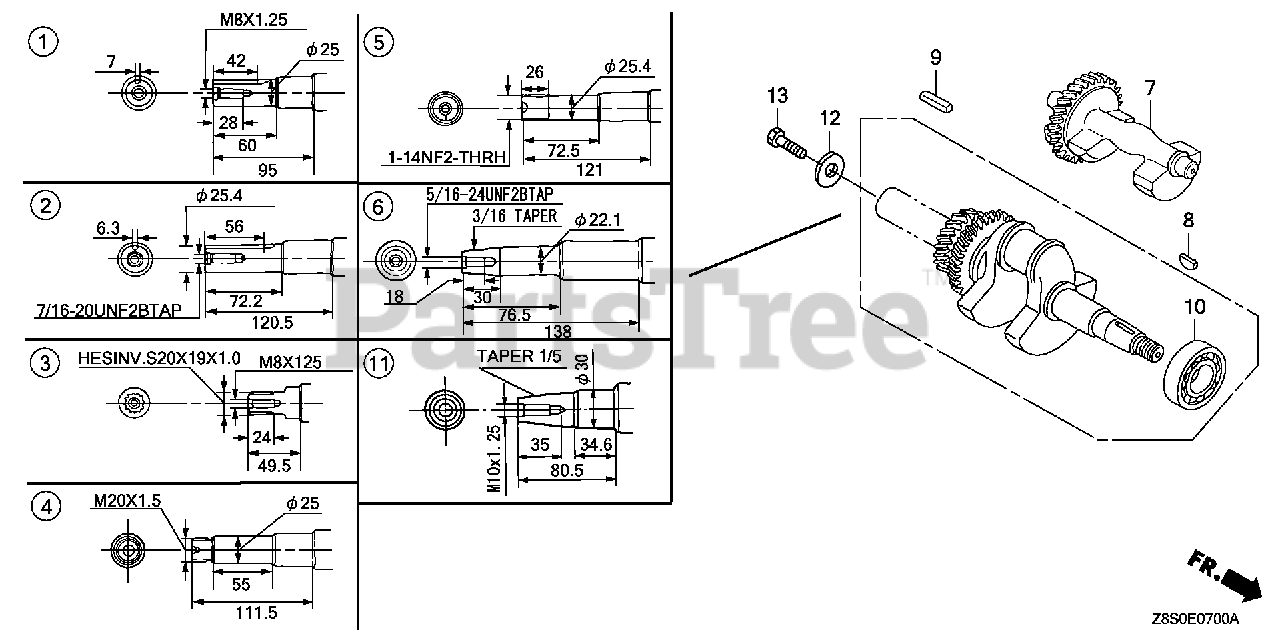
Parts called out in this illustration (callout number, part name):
3	CRANKSHAFT
7	WEIGHT, BALANCER
8	KEY, SPECIAL WOODRUFF (25X18)
10	BEARING, RADIAL BALL (6206 SH)
